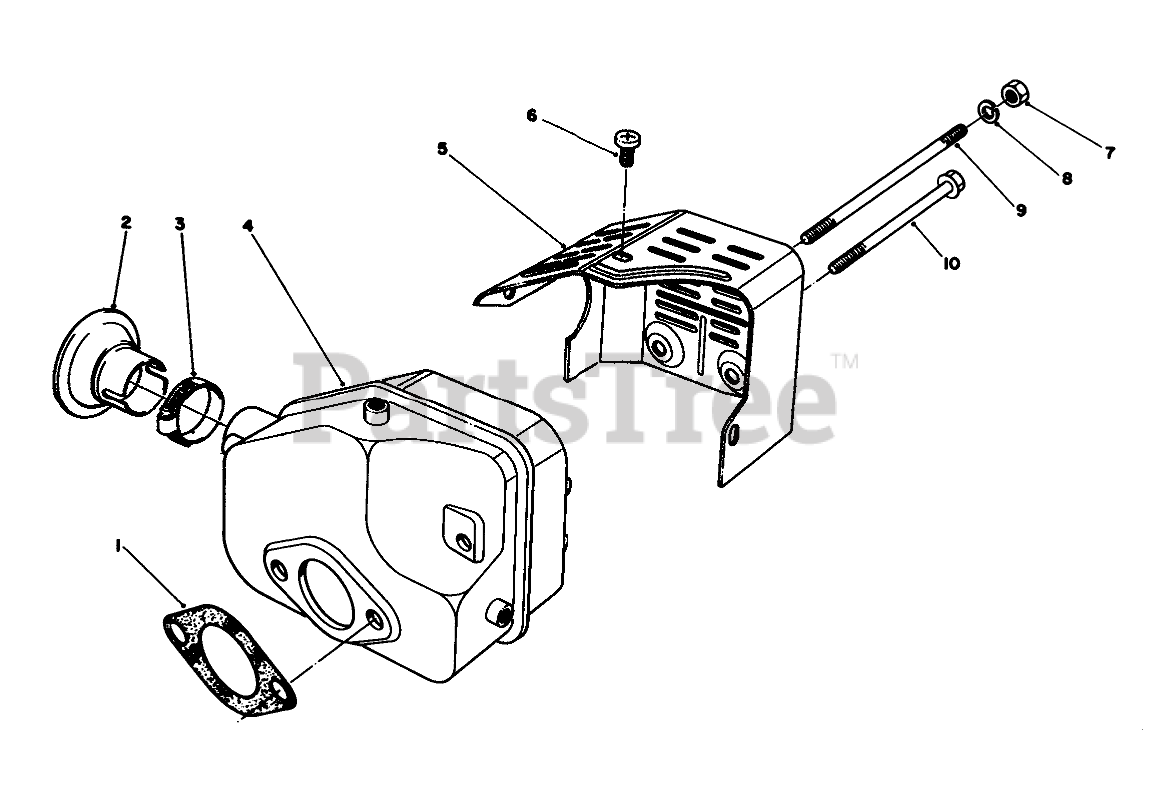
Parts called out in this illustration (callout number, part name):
1	GASKET
2	Arrestor-Spark
3	Clamp-Hose
4	Muffler
5	COVER
6	SCREW
8	WASHER-LOCK
